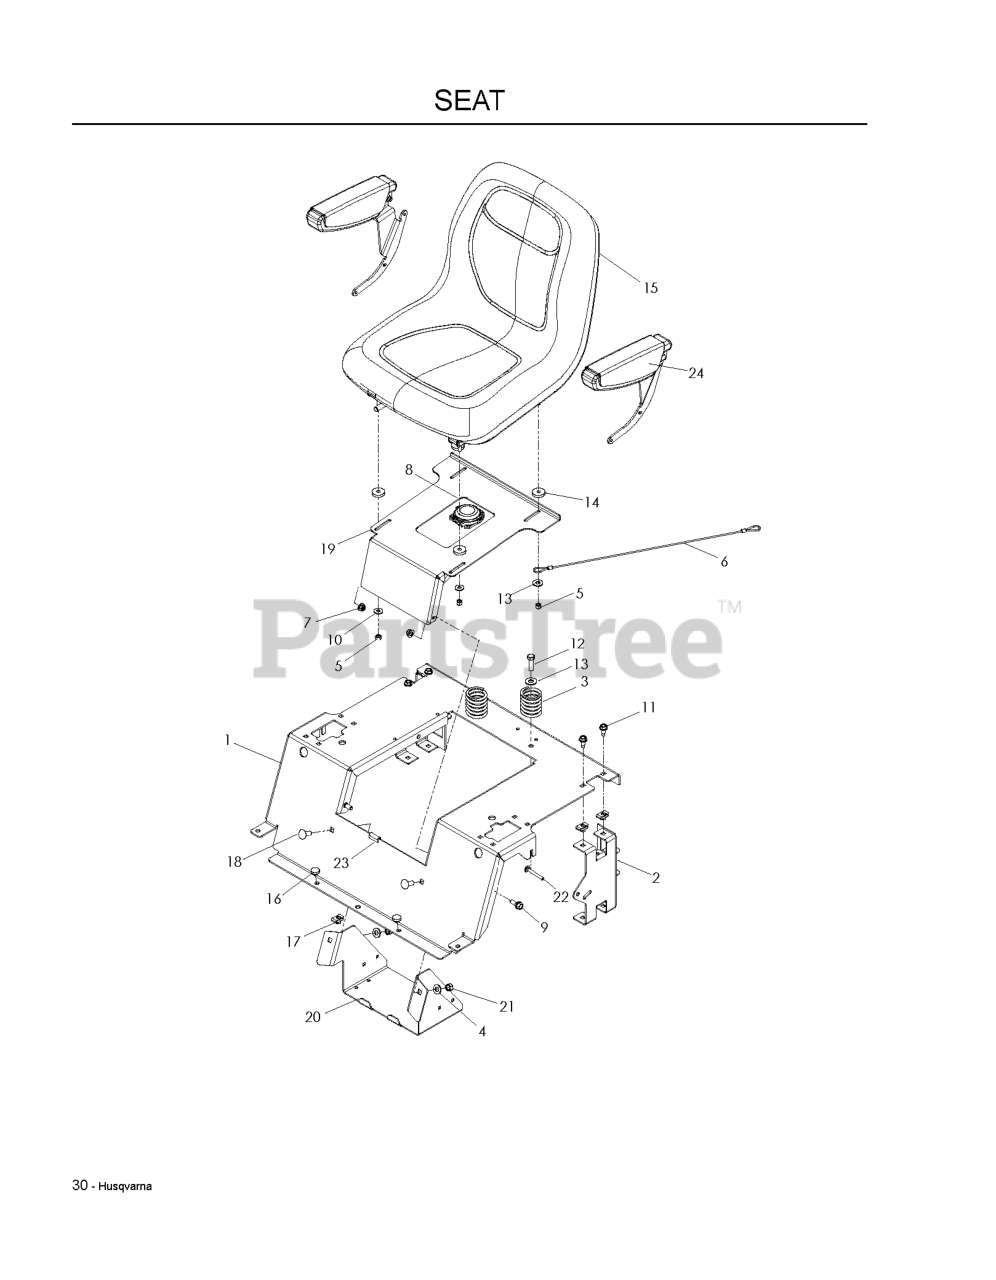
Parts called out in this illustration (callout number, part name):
1	SUPPORT, SEAT, FLAT ORANGE
2	SUPPORT, REAR SEAT, BLACK
3	SPRING, SEAT
4	WASHER 3/8 SAE FLAT
5	NUT 5/16 NYLOC
6	SEAT LANYARD
7	5/16-18 NYLOC FLANGE NUT
8	SWITCH, SEAT N/C
9	SB 5/16-18 HEX HD GD5, BLK ZN
10	WASHER 5/16 FLAT
11	BOLT 5/16-18 X 3/4
12	HCS 3/8C X 1 1/4 GR5
13	WASHER 3/8 FLAT
14	WASHER NYLON
15	SEAT, 15", LS
16	GROMMET, BUMPER
17	U-CLIP 5/16-18 NUT RETAINER
18	RHSNB 3/8C X 1
19	PAN, SEAT, ORG
20	BOX, BATTERY, BLACK
21	NUT 3/8-16 NYLOC
22	RHSNB 5/16-18 X 2-1/2 GR5 ZD
24	KIT, ARMREST, ONLY FITS ON
25	MOUNT, SPRING, RAM SEAT, BLK
